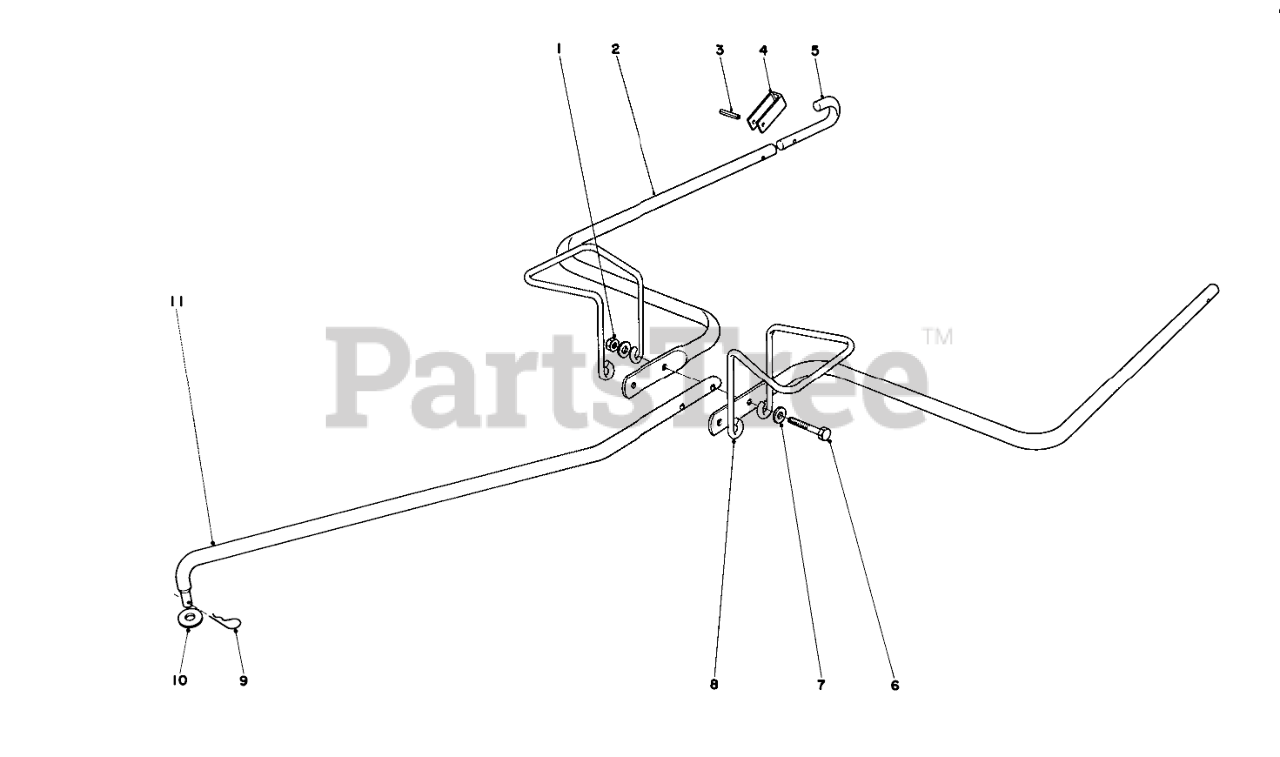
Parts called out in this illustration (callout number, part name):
1	NUT-LOCK, CONE
2	HITCH ARM
3	PIN-ROLL, SLOT
4	HITCH LOCK
5	HOOK HITCH ARM
6	SCREW-HH
7	WASHER-FLAT
8	Support Bag
9	PIN-COTTER
10	PUSH NUT
11	POLE HITCH
